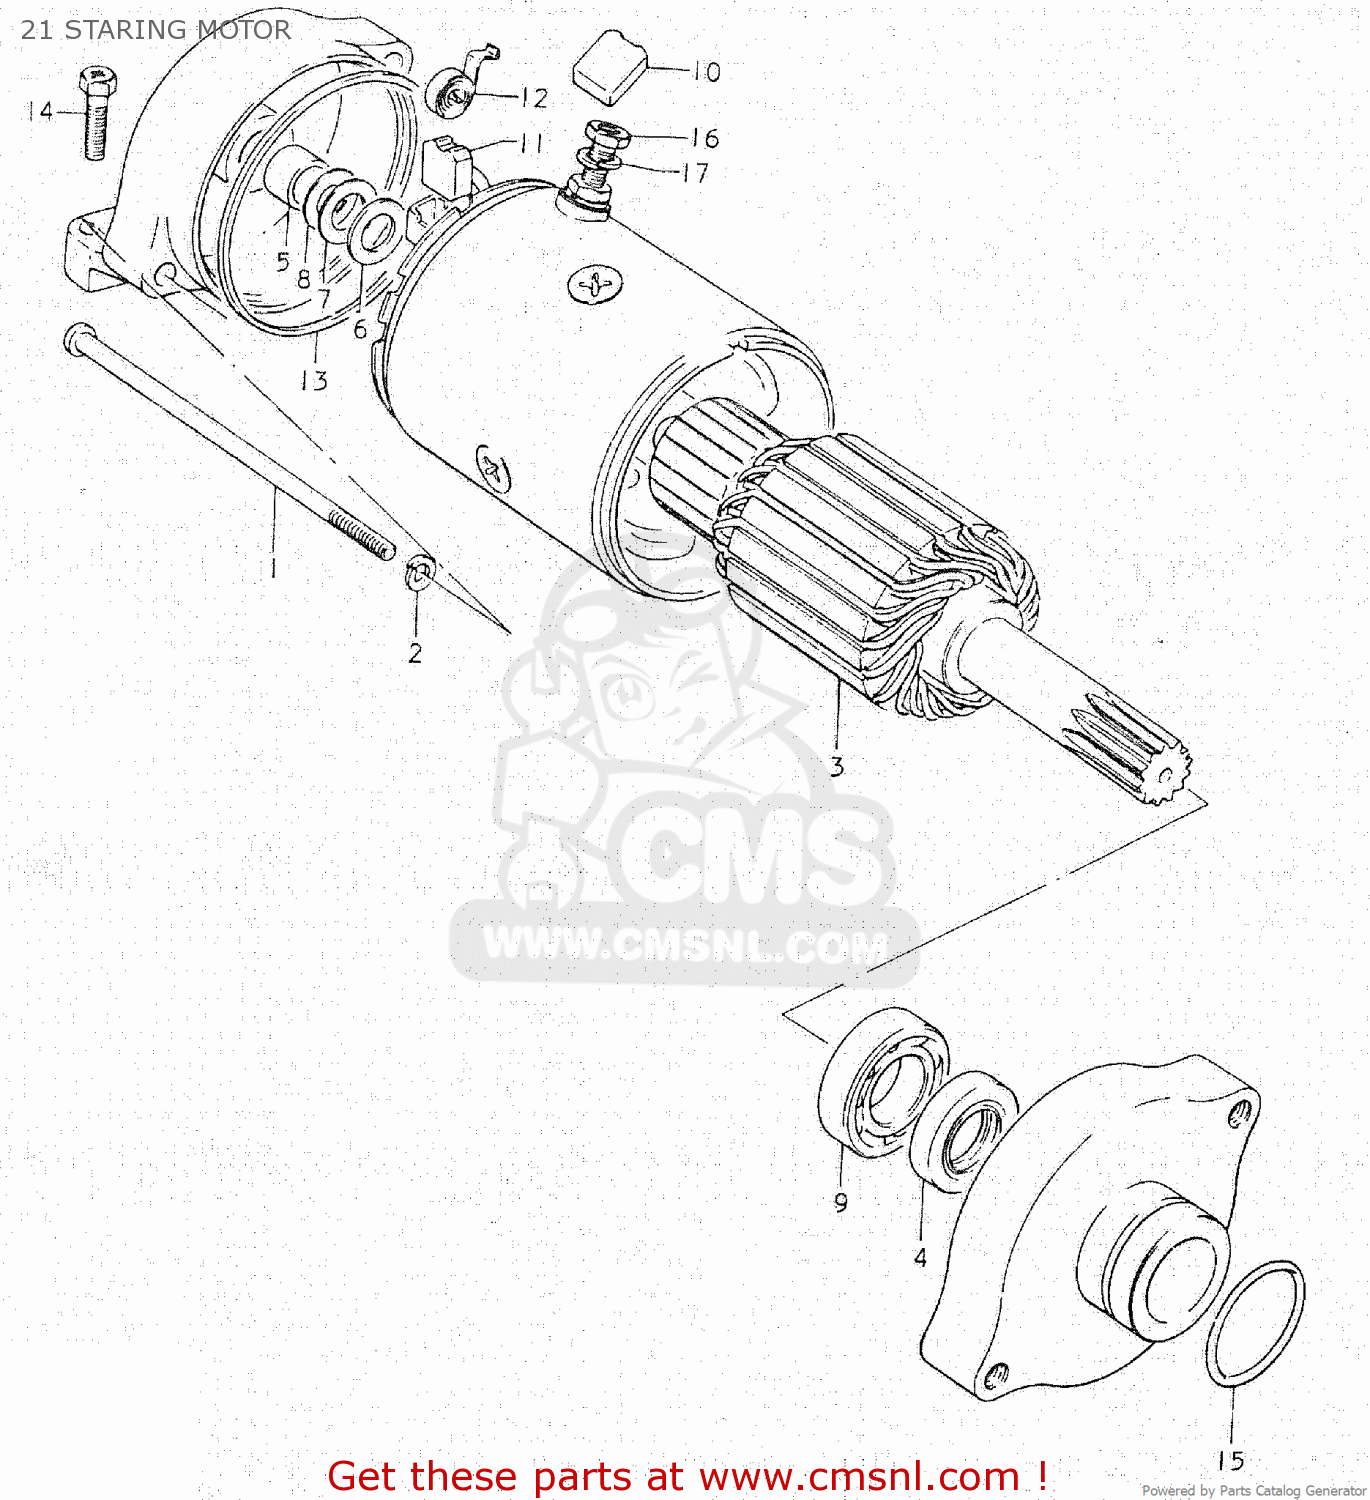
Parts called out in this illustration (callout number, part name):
1	BOLT
2	LOCK WASHER
3	ARMATURE
4	SEAL,OIL
5	BUSHING
6	SHIM, (1)
7	SHIM, (2)
8	SHIM, (3)
9	BEARING
10	BRUSH(-)
11	BRUSH(-)
12	SPRING
13	GASKET
14	SCREW
15	O RING(D:2,ID:24.5)
16	NUT 6MM
17	LOCK WASHER
